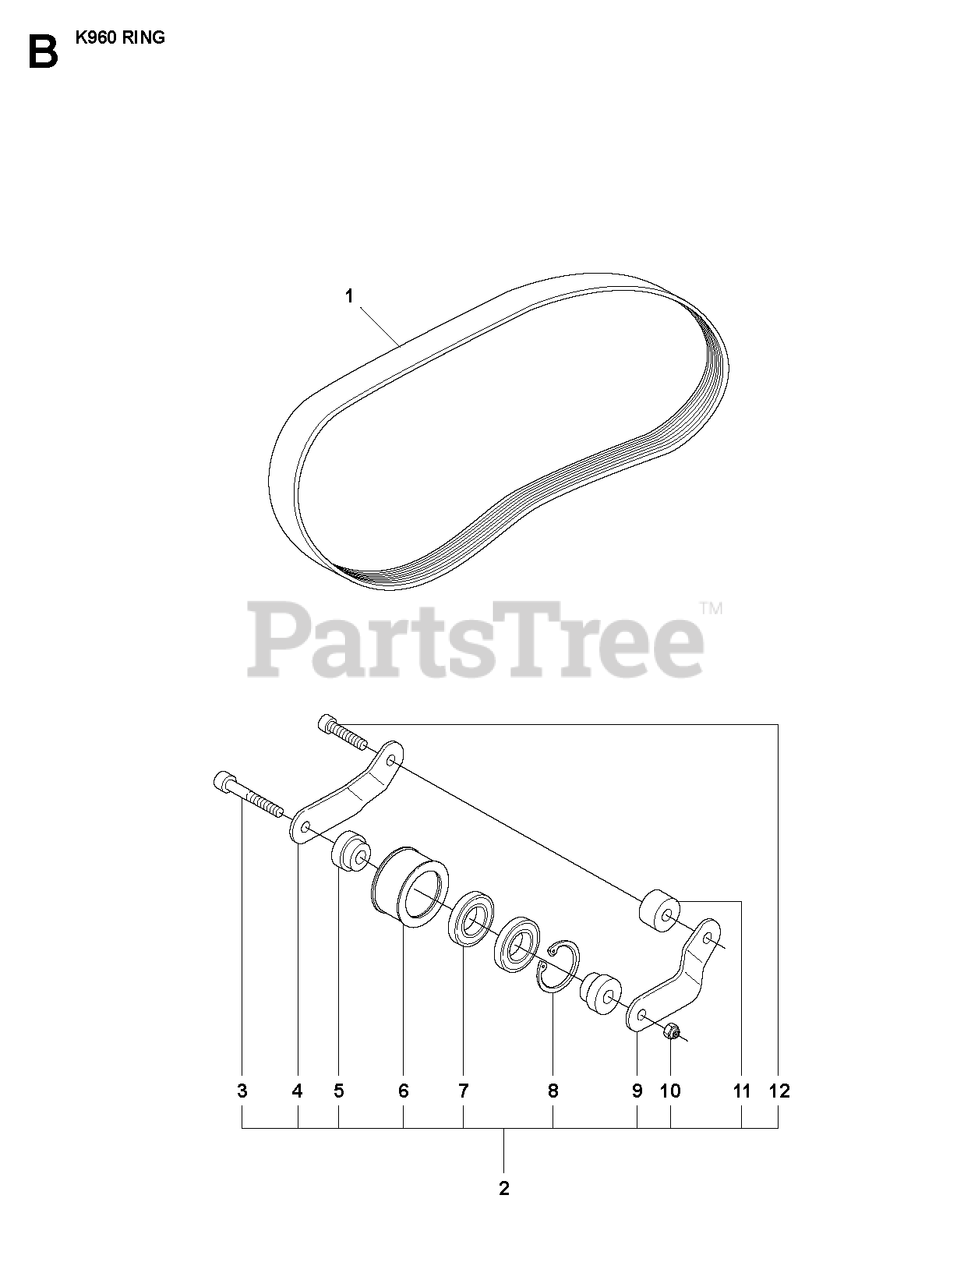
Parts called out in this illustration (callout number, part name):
2	BELT TENSIONER ASSYIncl. 3 - 12
3	SCREW ITXSCM
7	BALL BEARING
10	NUT
12	SCREW ITXSCM
